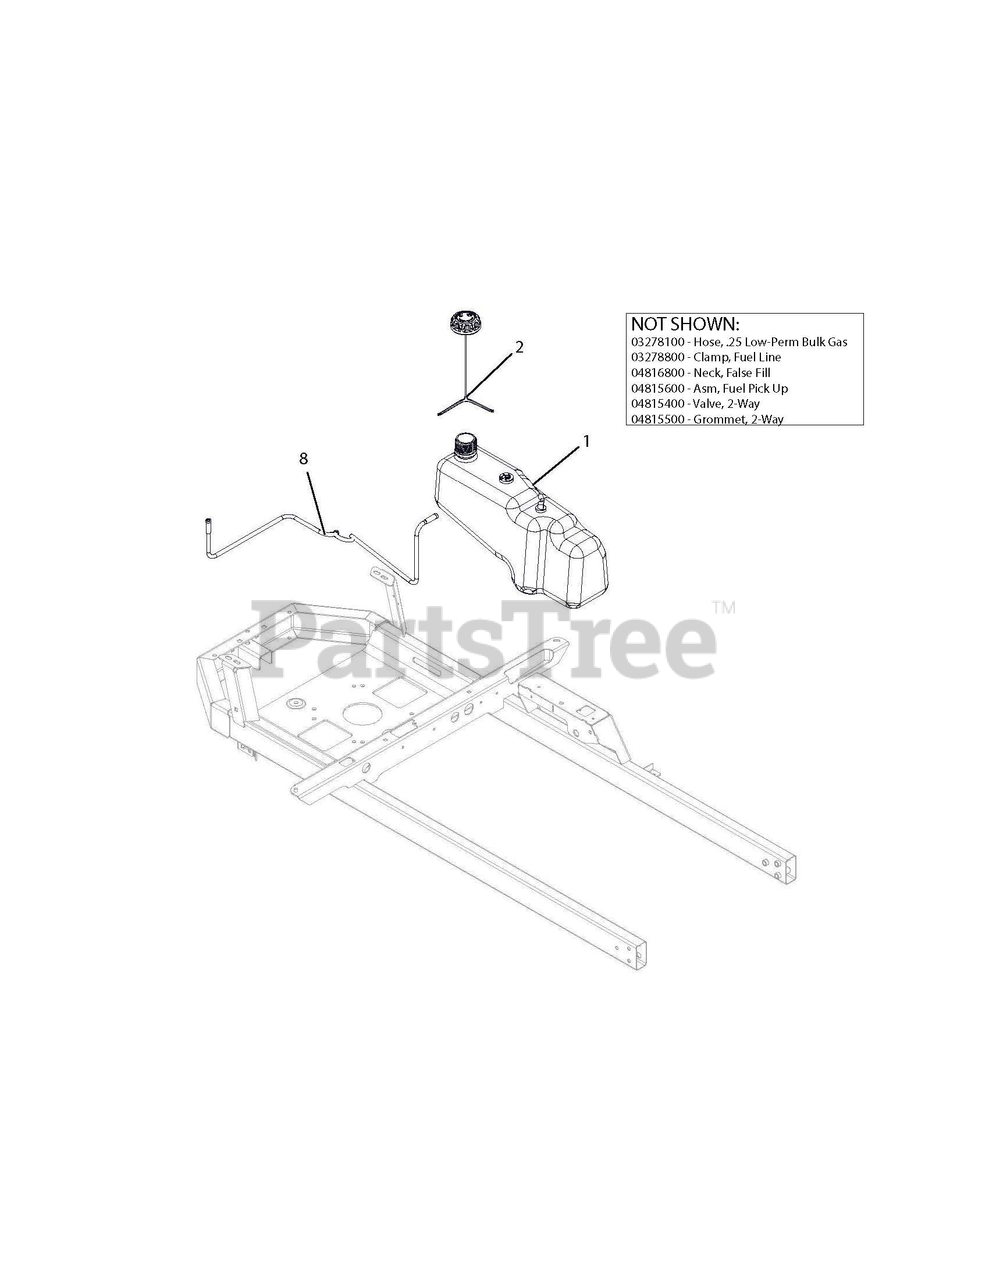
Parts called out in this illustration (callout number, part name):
1	ASM, TANK NON-PERM FUEL
2	CAP, FUEL VENT-IN 2.25" RATCHET
8	LINE, FUEL VENT
